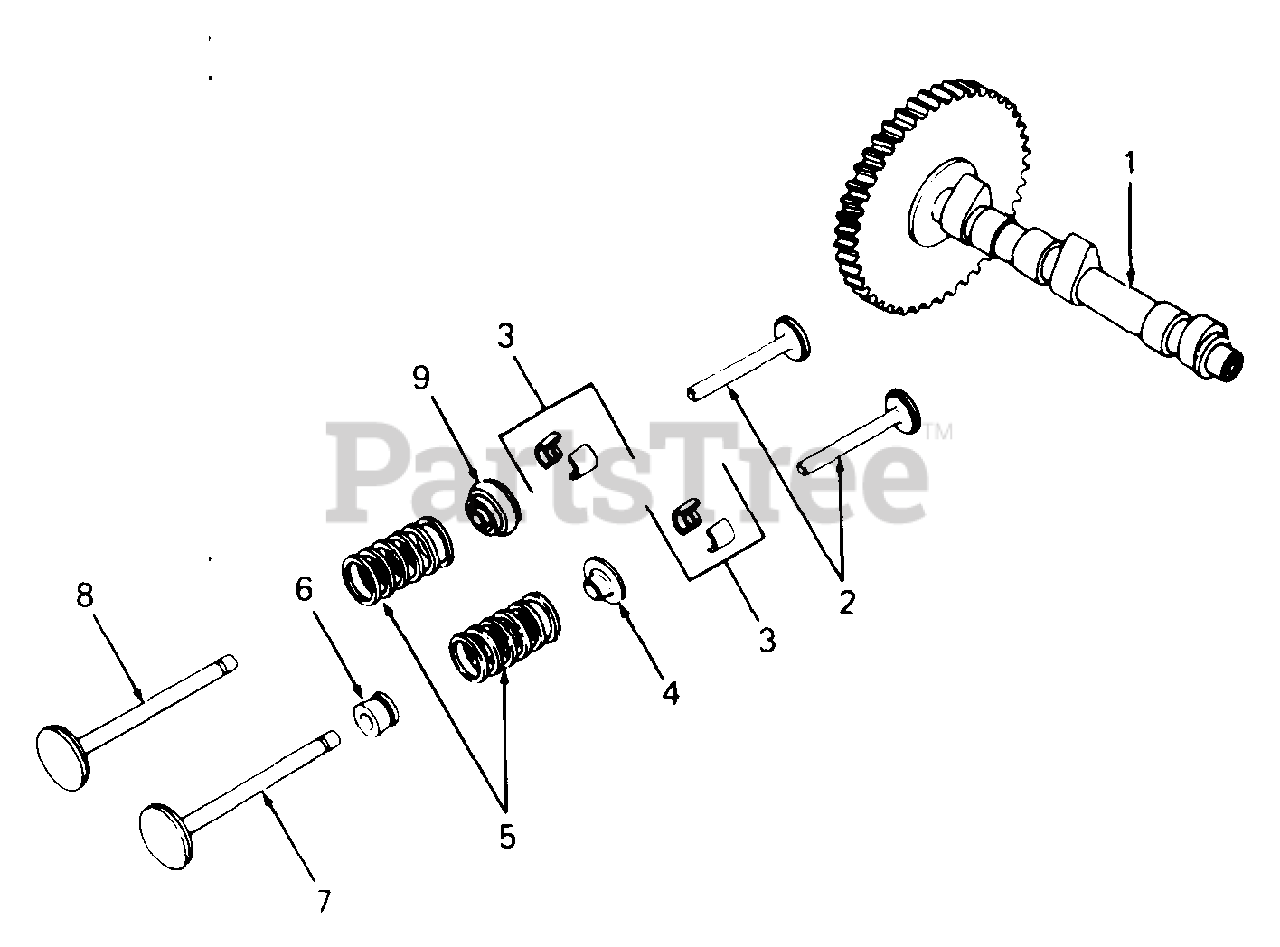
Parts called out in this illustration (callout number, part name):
1	Camshaft
3	Kit, Retainer
4	Retainer, Intake Valve
5	Spring, Valve
6	Seal, Intake Valve Stem
7	Valve, Intake
8	Valve, Exhaust
9	Rotator, Exhaust Valve
